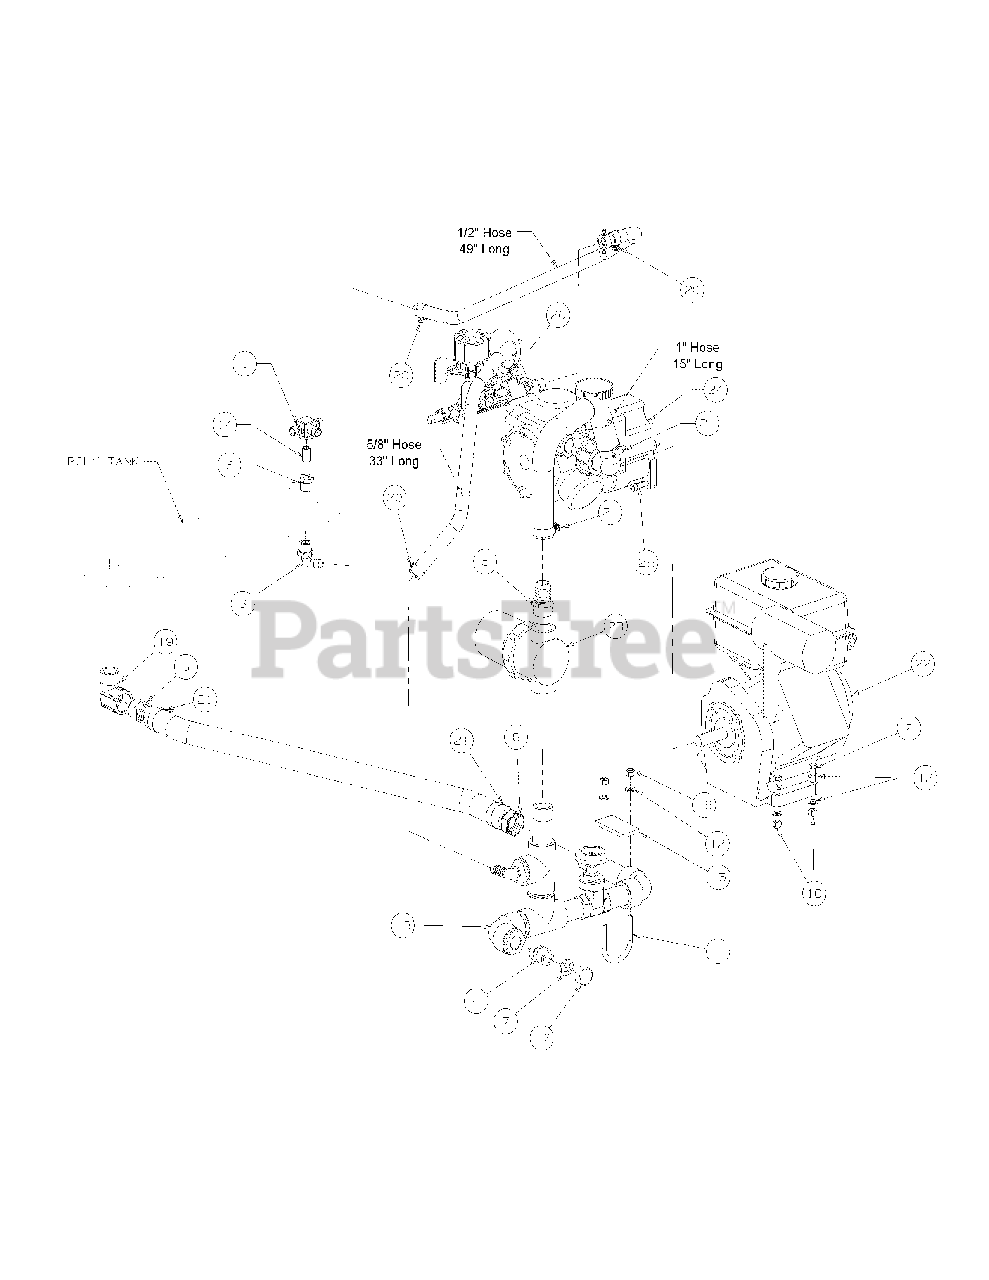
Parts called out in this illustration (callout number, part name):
1	Jet Agitator
2	Hex Cap Screw, 5/16-18, 1-3/4
3	1/2 NPT, 1/2 Nylon, Hose Barb
4	3/4 NPT, 3/4 Hose Thread Barb Fitting
5	1" NPT, 1" Nylon Hose Barb
6	1/4" NPT, 1/2" NPT,
7	Rubber Washer, 3/4"
8	Brass Hose Repair Coupling
9	Hose 1/2" by the ft.
10	Hose 1" by the ft.
11	U-bolt, 5/16-18 x 2
12	5/16 Flat Washer
13	Manifold Assembly
14	1/4" Close Nipple,
15	Rubber Pad, 1/4" x 1-1/2" x 3"
16	Nylock Nut, 5/16-18
17	Hose Cap, 3/4"
18	Hose 5/8"
19	Street Elbow, 1" NPT by 1"
20	1/2" x 7/8" Hose Clamp,
21	Hose Clamp, 7/8 x 1-1/4
22	5.5HP Kawasaki Engine
23	Nylon Bowl Strainer
24	Hypro Pump D-403
25	Socket Head Capscrew, M8-1.25 x 25
